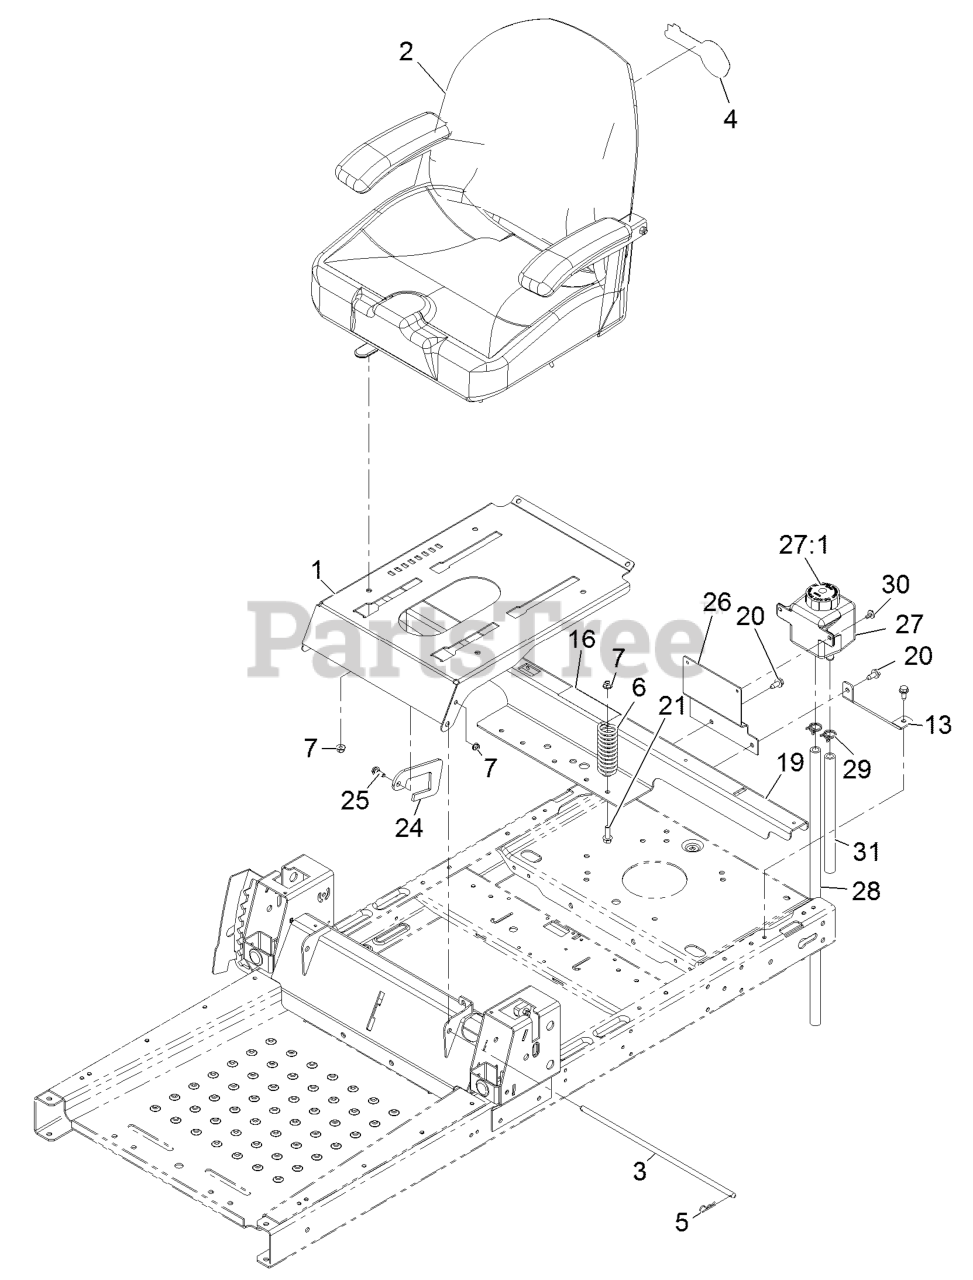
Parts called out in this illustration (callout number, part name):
2	SEAT ASM
3	ROD-STOP
5	PIN-COTTER
6	SPRING-COMPRESSION
7	NUT-HF, NI
13	SUPPORT-TANK, REAR
16	DECAL-SERVICE, CE
19	SUPPORT-POD
20	Screw-HWH 5/16-18 X 3/4 Tf
21	SCREW-HHF
24	STOP-SEAT
25	SCREW-SHOULDER
26	MOUNT-TANK
27	TANK-HYD
27:1	CAP-RESERVOIR, HYD
28	HOSE-OVERFLOW
29	CLAMP-HOSE
30	SCREW-HHFTF
31	HOSE-OVERFLOW
